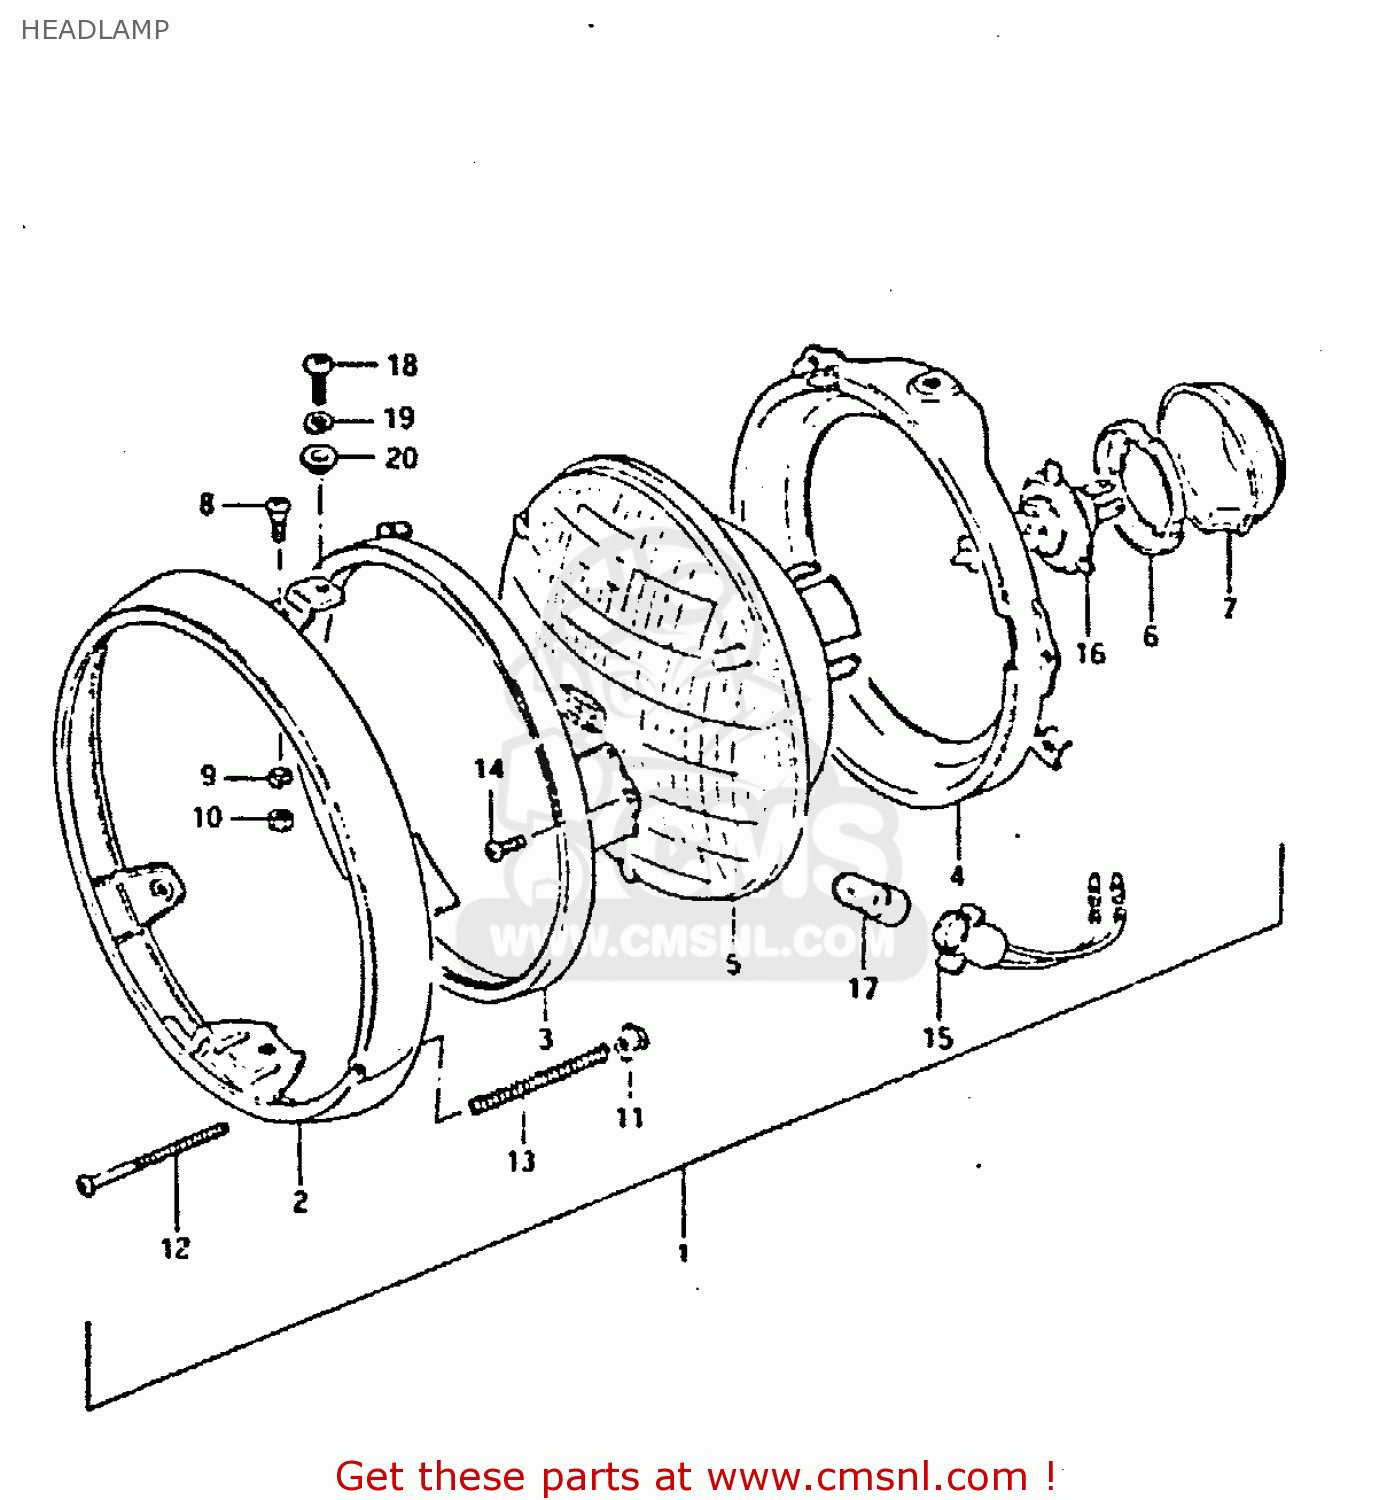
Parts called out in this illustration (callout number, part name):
1	HEADLAMP ASSY
2	RIM
3	RETAINING RING
4	RING
5	UNIT
6	SETTING,BULB
7	COVER,HEADLAMP SOCKET
8	H/LAMP LENS UNIT FITING SCRE
9	LOCK WASHER
10	NUT
11	NUT
12	SCREW,HEADLAMP ADJUST
13	SPRING,ADJUSTING
14	SCREW
15	SOCKET
16	BULB(12V60/55W,H4)
17	BULB
18	SCREW
19	WASHER,LOCK
20	WASHER
